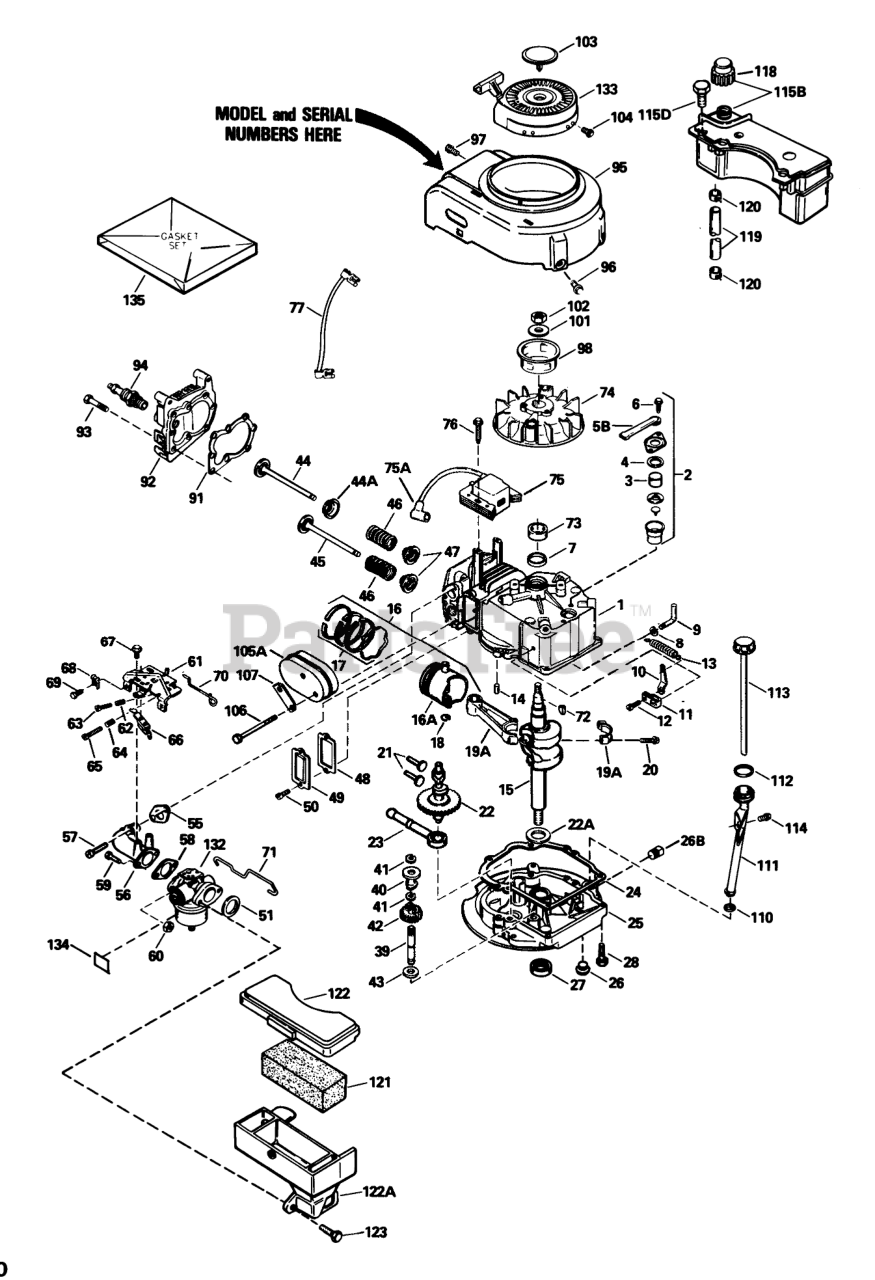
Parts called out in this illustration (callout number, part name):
1	Cylinder Assembly (Incl. Ref. #7 & 14)
2	Breather Assembly (Incl. Ref. #3-6)
3	Element-Breather
4	Gasket-Breather
5B	Tube, Breaker
6	Screw (10-24 x 9/16)
7	Seal-Oil
8	Washer-Flat
9	Rod-Governor (Incl. Ref. #8)
10	Governor Lever
11	Clamp-Lever, Governor
12	Screw
13	Spring Governor
14	Pin-Dowel
15	Crankshaft Assembly
16	Piston-Pin & Ring Assy. (Std.) (Incl. Ref. #16A, 17 & 18)
16	Piston-Pin & Ring Assembly (.010 oversize) (Incl. Ref. #16A, 17 & 18)
16	Piston-Pin & Ring Assembly (.020 oversize) (Incl. Ref. #16A, 17 & 18)
16A	Piston & Pin Assembly (Std.) (Incl. Ref. #18)
16A	Piston & Pin Assembly (.010 oversize) (Incl. Ref. #18)
16A	Piston & Pin Assembly (.020 oversize) (Incl. Ref. #18)
17	Ring Set-Piston (Std.)
17	Ring Set, Piston(.0100versize)
17	Ring Set (.020" OS)
18	Ring-Retaining, Piston Pin
19A	Rod Assembly-Connecting (Incl. Ref. #20)
20	Bolt-Rod, Connecting
21	Lifter-Valve
22	Camshaft(Mech.Comp. Release)
22A	Washer-Thrust
23	Oil Pump ASM
24	Gasket
25	Flange-Mounting (Incl. Ref. #26, 26B, 27 & 39)
26	Plug Oil Drain
26B	Plug-Pipe
27	Seal-Oil
28	Screw (1/4-20 x 1-1/4)
39	Shaft-Governor
40	Spool-Governor
41	Ring-Retaining
42	Gear Assembly-Governor (Incl. Ref. #43)
43	Washer
44	Valve-Intake (Std.) (Incl. Ref. #47)
44	Valve-Intake (1/32" oversize) (Incl. Ref. #47)
44A	Seal Assy., Intake
45	Valve, Exhaust (Std.) (Incl. Ref. #47)
45	Valve-Exhaust (1/32" oversize) (Incl. Ref. #47)
46	Spring-Valve
47	Cap-Valve, Spring
48	Gasket-Cover, Valve
49	Cover-Valve
51	Gasket-Cleaner, Air
55	Gasket-Intake Pipe
56	Pipe-Intake (Incl. Ref. #55)
57	Screw (1/4-20 x 1)
59	Screw (1/4-28 x 7/8)
60	Nut and Lock Washer (1/4-28)
61	Bracket Assembly-Control (Incl. Ref. #62-66)
62	61709/GIL1515A/95-5
63	Screw
64	Spring-Compression
65	Screw
66	Terminal
67	Screw (10-24 x 9/16)
68	Conduit
69	Screw (10-32 x 3/8)
70	2035A67 ADD.ASSEMBL
71	Link-Throttle
72	Key-Flywheel
74	Flywheel
75	Solid State
75A	Cover-Spark Plug
76	Screw
77	Wire-Ground
91	Gasket-Cylinder Head
92	Head-Cylinder
93	Screw (5/16-18x1-1/2)
94	Spark Plug-Resistor (R J19 L M)
95	Housing-Blower
96	Screw (1/4-20 x 1/2)
97	Screw (10-24 x 9/16)
98	Hub-Starter
101	Washer-Belleville
102	Nut-Flywheel
103	Plug Starter
104	Screw, Hex Hd.
105A	Muffler
107	Plate-Lock
111	Oil Fill Tube
113	Dipstick
114	Screw (10-32 x 1/2)
115B	Tank Assembly (Incl. Ref. #118 & 120)
115D	Screw (10-32 x 35/64)
118	Cap-Fuel
119	Line-Fuel
120	Clamp-Line, Fuel
121	Filter-Air Cleaner
122	Cover-Air Cleaner
122A	Body Air cleaner
132	Carburetor (Incl. Ref. #58)
133	Starter-Rewind
134	Decal-Primer
135	Gasket Set (Incl. Items Marked )
